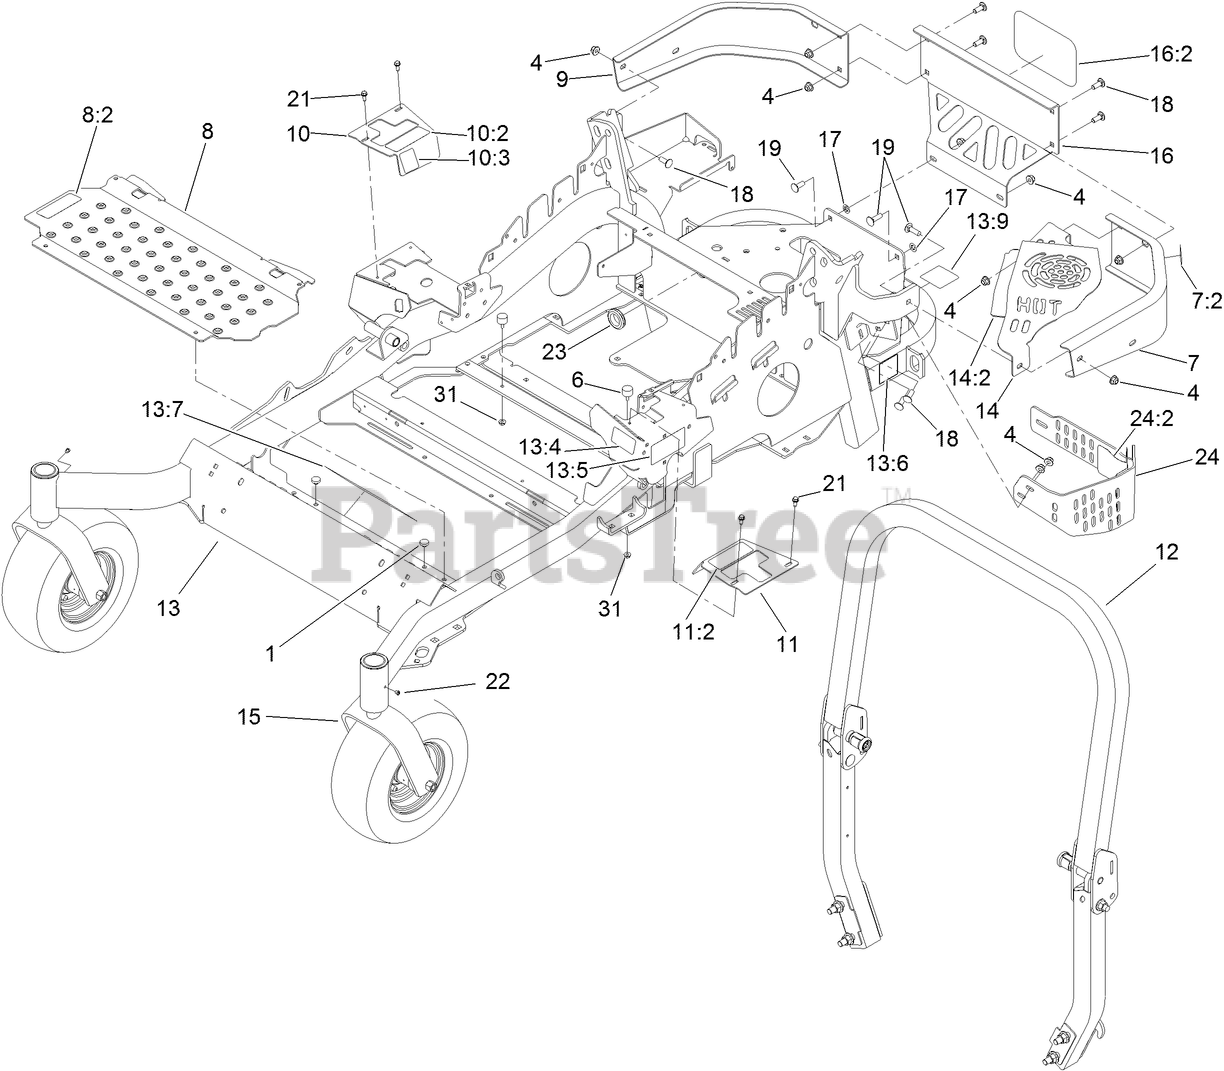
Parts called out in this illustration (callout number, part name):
1	BUMPER
4	NUT-HF, NI
7	LH REAR BUMPER ASM
7:2	DECAL-WARNING
8	FLOORPAN ASM
8:2	DECAL-COVER, MISSING
9	BUMPER-REAR, RH
10	RH MOTION CONTROL COVER ASM
10:2	DECAL-CONTROL, MOTION
10:3	DECAL-PARK BRAKE, CE
11	MOTION CONTROL COVER ASM
11:2	DECAL-CONTROL, MOTION
12	ROPS ASM
13	MAIN FRAME ASM
13:4	DECAL-FUEL FILL, CE
13:6	DECAL-HAZARD, PINCHED FINGER
13:7	DECAL-DANGER SLOPE W/ROPS
13:9	DECAL-BYPASS
14	MUFFLER GUARD ASM W/FOIL
14:2	FOIL-TAPE
15	FRONT CASTER ASM
16	REAR GUARD ASM
16:2	DECAL
17	NUT-PUSH
18	SCREW-CARR
19	BOLT-CARR
21	SCREW-HWH
23	GROMMET
24	LH LOWER MUFFLER GUARD ASM
24:2	DECAL-WARNING
31	NUT-HF
